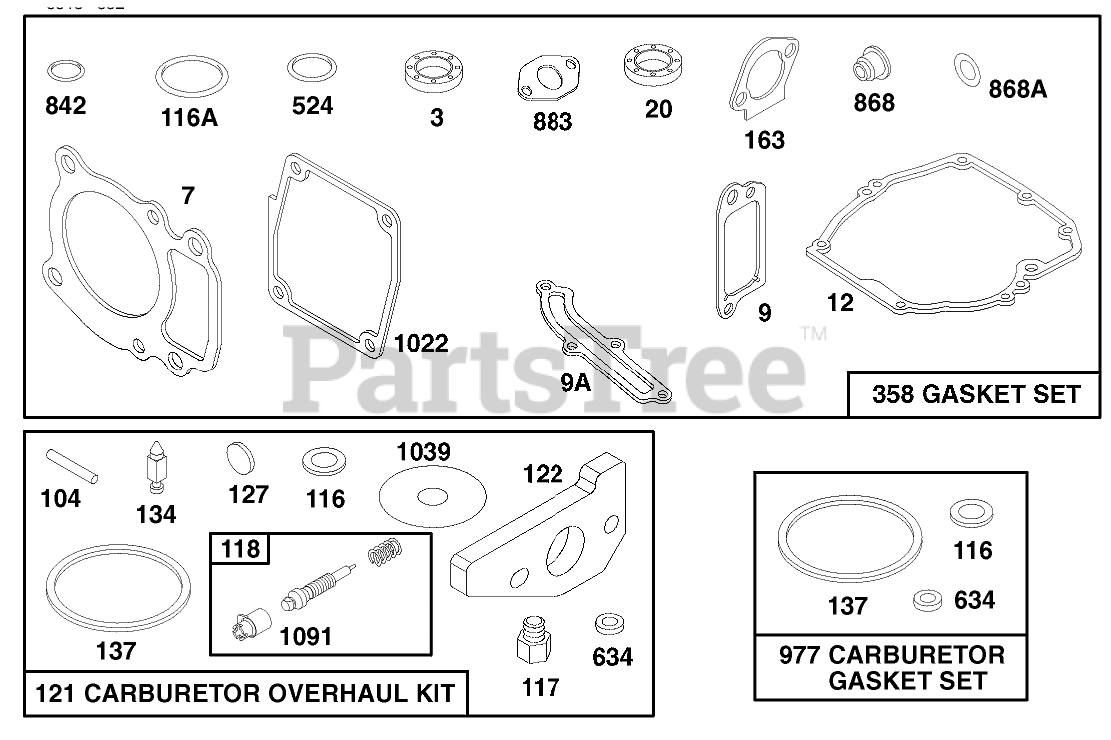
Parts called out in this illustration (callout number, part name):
3	SEAL - OIL
7	CYLINDER HEAD GASKET
9	BREATHER GASKET
9A	GASKET-BREATHER
12	ENGINE BASE GASKET
20	SEAL-OIL
104	FLOAT HINGE PIN
116	SEALING GASKET
116A	O RING SEAL
117	Jet-Main
118	VALVE/SPRING - NEEDLE
121	KIT-CARBURETOR OVERHAUL
122	ADAPTER ASSEMBLY
127	PLUG - WELCH
134	Valve-Inlet (Includes Seat)
137	FLOAT BOWL GASKET
163	AIR CLEANER GASKET
358	GASKET SET
524	O-RING
634	SEAL WASHER
842	O-RING
868	SealAssy-Valve
868A	Seal-Valve
883	EXHAUST GASKET
977	CARBURATOR GASKET SET
1022	ROCKER COVER GASKET
1039	FLOAT LIMITER
1091	CAP - LIMITER
